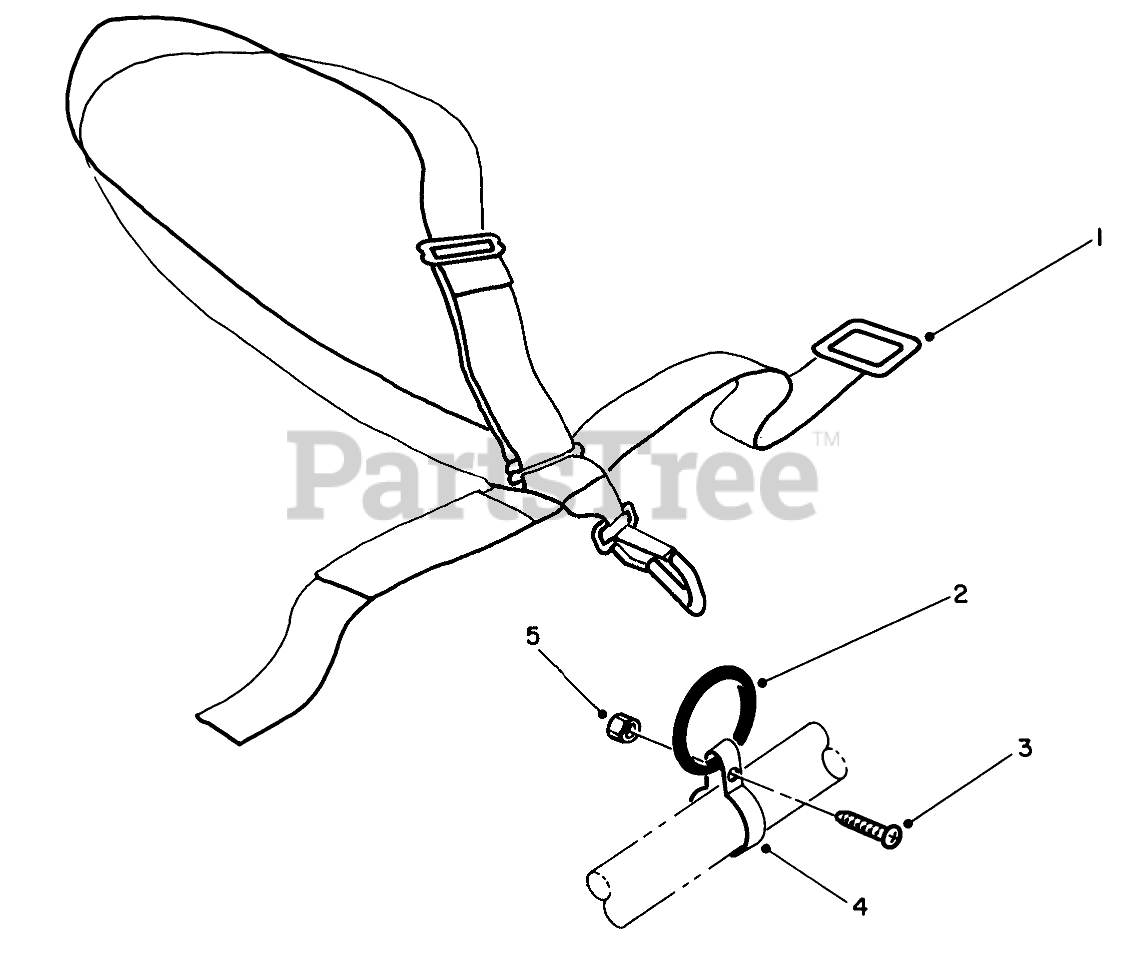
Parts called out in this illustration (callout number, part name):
1	Deluxe Harness
2	Ring
4	Clamp
5	Nut
